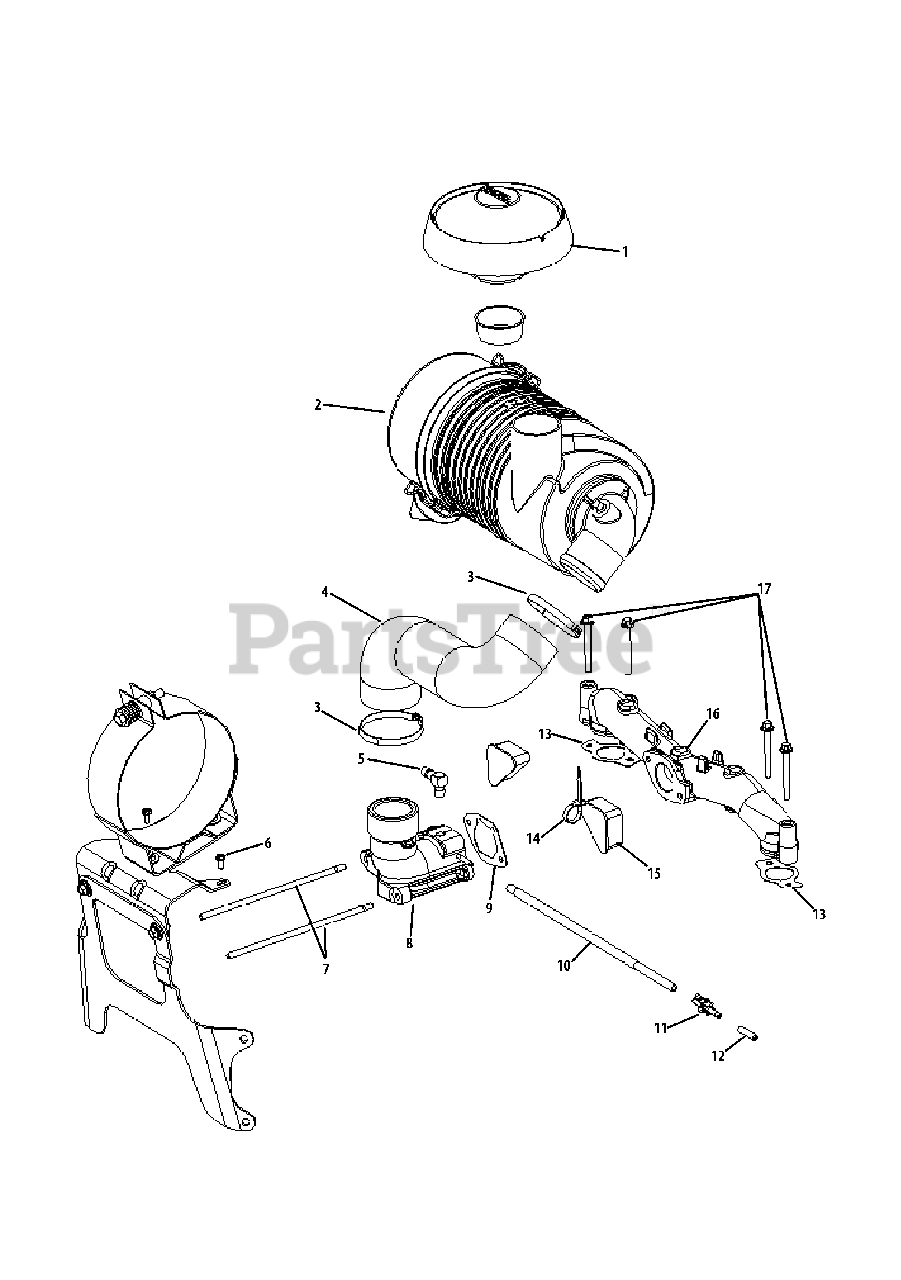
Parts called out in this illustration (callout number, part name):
2	Air Cleaner Canister
4	Air Cleaner Hose
5	Connector Hose
6	Screw, #8-18 X 1/2
7	Stud, M6 x 1.0 x 180
9	Air Cleaner Base Gasket
10	Evaporative Hose, 20
11	Evaporative Connector
13	Intake Manifold Gasket
15	Blower Housing Cover
16	Intake Manifold
17	Flange Screw, M6 x 1.0 x 55
